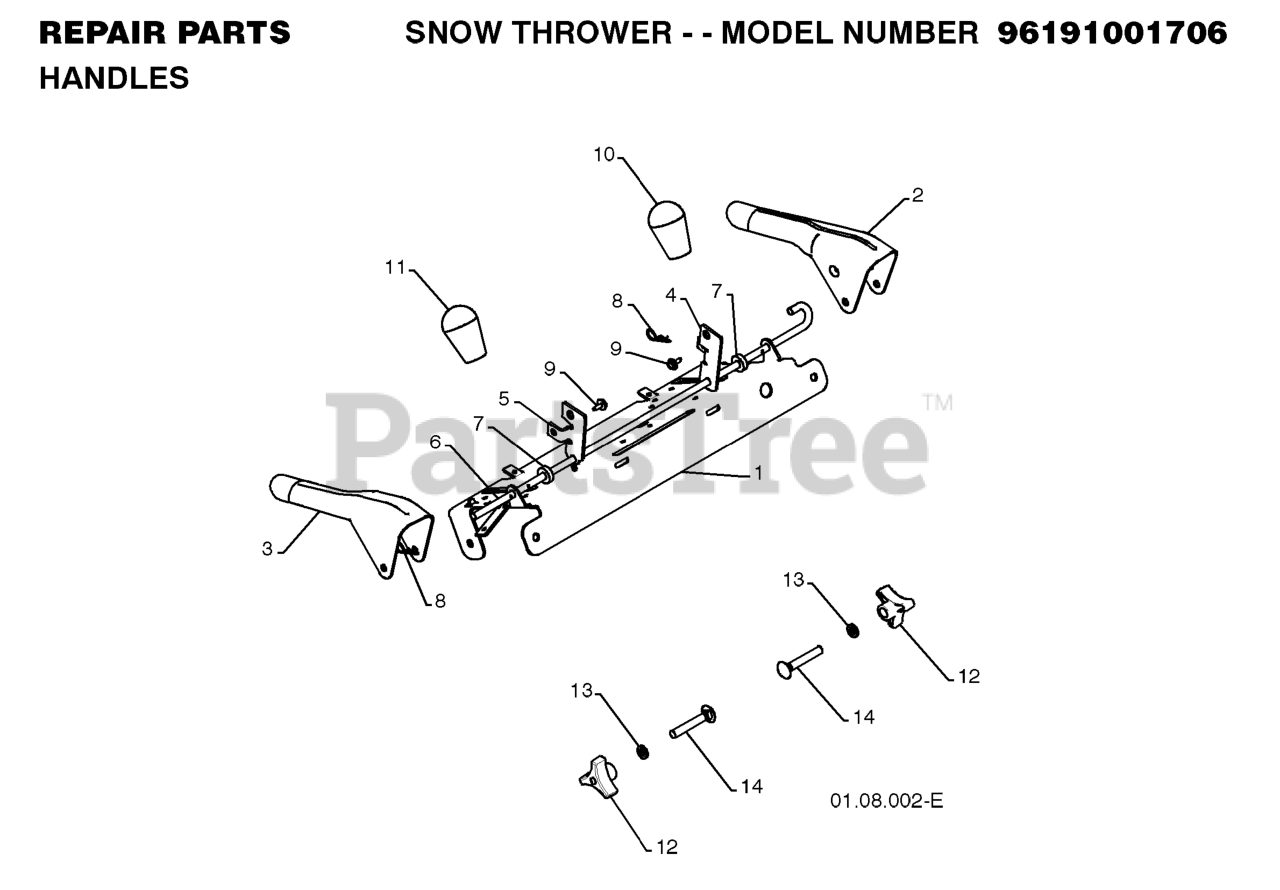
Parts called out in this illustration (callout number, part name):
1	CONTROL PANEL
2	LEVER.CONTROL.LH.PNT
4	TRACTION ROD ARM
5	ARM.IMPELLER.ROD.YZ
6	BAIL.CONTROL.INTERLOCK
7	SPACER.CONTROL.LEVER
8	SPRING RETAINER
10	KNOB LEVER, BLACK
11	RED KNOB SHIFTER
12	KNOB.HANDLE.3/8.TRI-POINT.BLAC
13	WASHER
14	BOLT 3/8-16 X 2-1/4
